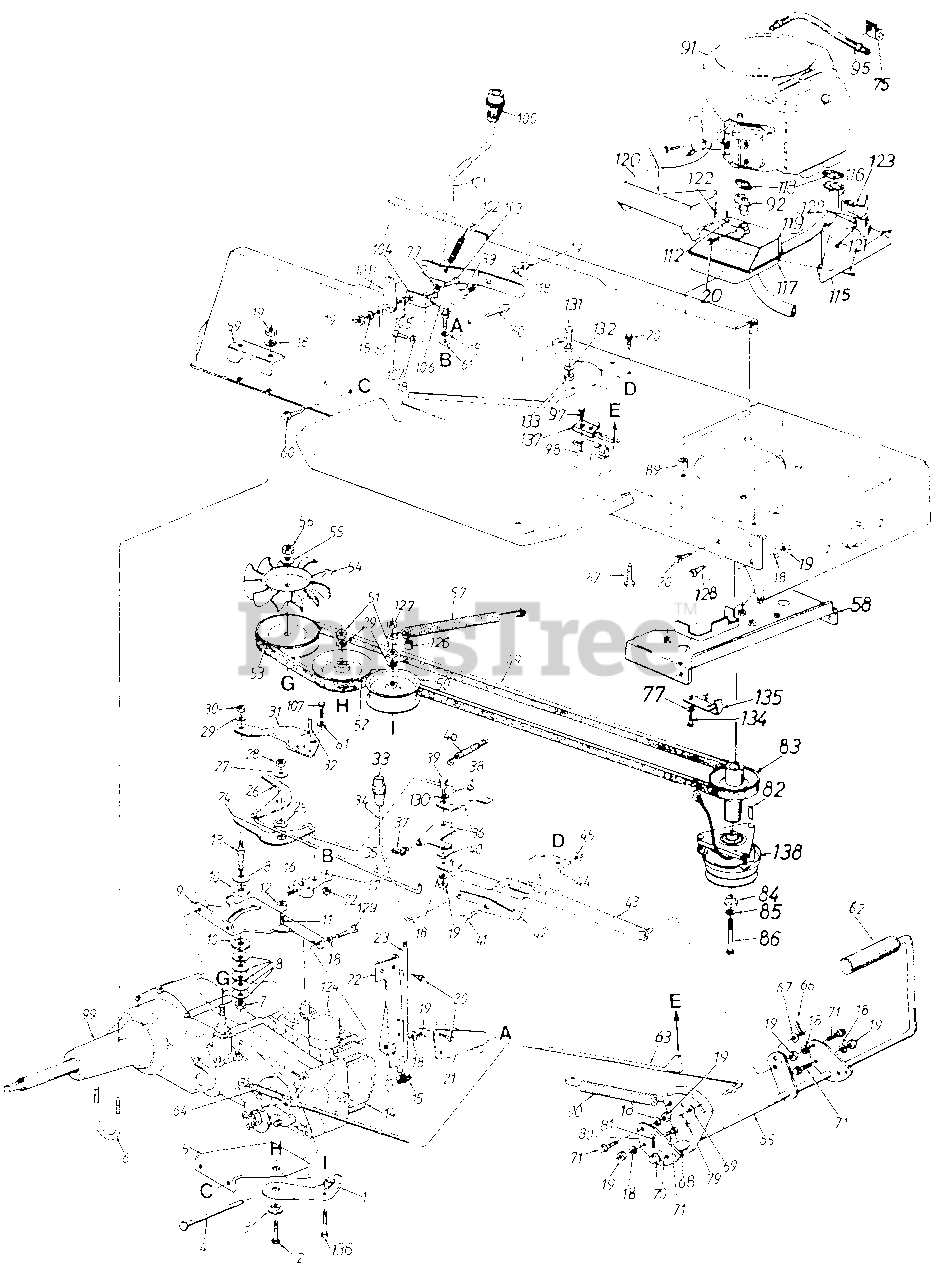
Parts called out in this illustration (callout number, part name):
1	Idler Bracket
2	Hex Bolt 3/8-16 x 2.0" Lg.
3	Shld. Spacer.625" I.D.
4	Hex Bolt 5/16-18 x 4.5" Lg. (Grade 5)
5	Idler Plate
6	U-Bolt 5/16-18 x 1.75" Lg.
7	Hex L-Nut 3/8-24 Thd.
8	Bell-Wash. .40" I.D. x 1.13
9	Mounting Bracket
10	Friction Washer
11	Rib Neck Bolt 5/16-24 x .84" Lg.
12	Spacer
14	Hydrostatic Pump
15	Rubber Washer .33" I.D.
16	Set Screw
17	Pintle Shift Lever
18	L-Wash. 5/16" I.D.
19	Hex Nut 5/16-18 Thd.
20	Hex TT-Tap Scr. 1/4-20 x .5"
21	Reinforcement Plate
22	Transmission Torque Brkt.
23	Release Valve Rod
24	Reverse Arm
25	Spring Washer .625" I.D.
26	Forward Arm
27	Fl-Wash. .344" I.D. x 1.0"
28	Hex Cent. L-Nut 5/16-24 Thd.
29	L-Wash. 3/8" I.D.
30	Hex Nut 3/8-24 Thd.
31	Pintle Arm Ext. Plate
32	Roll Pin 114" Dia. x .75" Lg.
33	Knob
34	Lock-Up Rod
35	Connection Rod
36	Balancer Bracket
37	Rod End Clevis Clips R.H.
38	Rod End Clevis Clips L.H.
39	Shld. Bolt .437" Dia. x .268"
40	Fl-Wash. .344" I.D. x 1.12"
41	Shld. Bolt .437" Dia. x .35"
42	Lock-Up Bracket
43	Neutral Return Brkt. Ass'y.
44	Bracket
45	Hex Cent. L-Nut 5/16-18 Thd.
46	Ext. Spring 2.5" Lg.
49	"V"-Belt
50	Flat Idler
51	Hex Nut 3/8-16 Thd.
52	Idler Pulley 4.0" O.D.
53	Transmission Pulley
54	Hydro Fan
55	Bell-Wash. .56" I.D. x 1.125"
56	Hex Jam Nut 9/16-18 Thd.
57	Extension Spring
58	Belt Guard Brkt. Ass'y.
59	Bracket
60	Hex B-Tap Scr. 5/16-18 x .5"
61	Flat Tooth Washer 5/16" I.D.
62	Foot Pad
63	Brake Rod Ass'y.
64	Ext. Spring 3.67" Lg.
65	Clutch Brake Pedal Ass'y.
66	Intern. Cotter Pin 5/16" Dia.
67	Fl-Wash. .385" I.D. x .62"
68	Spacer.63" I.D.
69	Fl-Wash. .385" I.D. x .62"
70	Fl-Wash. .635" I.D. x 1.0"
71	Hex TT-Tap Scr. 5/16-18 x 7/8"
72	Hex Nut 5/16-24 Thd.
75	Clamp
77	Bell-Wash. .345" I.D. x .88"
79	Cotter 3/32" Dia. x .75" Lg.
80	Pedal Brkt.
81	Cotter Pin 3/32" Dia. x 1.0" Lg.
82	Sq. Key 1/4" x 1.5"
83	Engine Pulley
84	Shld. Spacer.445" I.D.
85	L-Wash. 7/16" I.D. (H.D.)
86	Hex Bolt 7/16-20 x 1.5" Lg.
87	Hex TT-Tap Scr. 3/8-16 Thd.
89	Spacer 5/16" I.D.
90	Extension Spring 6.11" Lg.
91	Engine
92	Inlet Tube Ass'y.
95	Hydraulic Hose 13" Lg.
97	Truss Mach. B-Tap Scr. #10 x .5" Lg.
98	Safety Switch (Clutch)
99	Transaxle
100	Shift Knob
101	Speed Selector Lever Ass'y.
102	Ext. Spring 2.75" Lg.
103	Hex Bolt 5/16-18 x 1.25" Lg.
104	Connection Brkt.
105	Shoulder Nut
106	Ball Joint 5/16-24 Thd.
107	Hex Bolt 5/16-24 x .75" Lg.
112	Bolt w/Washer
115	Muffler Heat Shield Front
116	Formed Tube Ass'y.
117	Exhaust Muffler Sub Ass'y.
118	Gasket
119	Muffler Ass'y. Comp.
120	Muffler Heat Shield
121	Hex Wash. Tap Scr. #10 x .5" Lg.
122	Speed Nut #10-24 Thd.
123	Front Heat Shield Ext.
124	Reservoir
126	Spacer .375" I.D. x .503
127	Hex Jam Nut 3/8-16 Thd.
128	Hex TT-Tap Scr. 5/16-18 x .62"
129	Hex Bolt 5/16-18 x 4.75" Lg.
130	Spr.-Wash. .445" I.D. x .75"
131	Hex Bolt 1/4-20 x 1.25" Lg.
132	L-Wash. 1/4" I.D.
133	Hex Nut 1/4-20 Thd.
134	Hex Bolt 5/16-18 x .75" Lg.
137	Switch Plate
138	Electric Clutch
